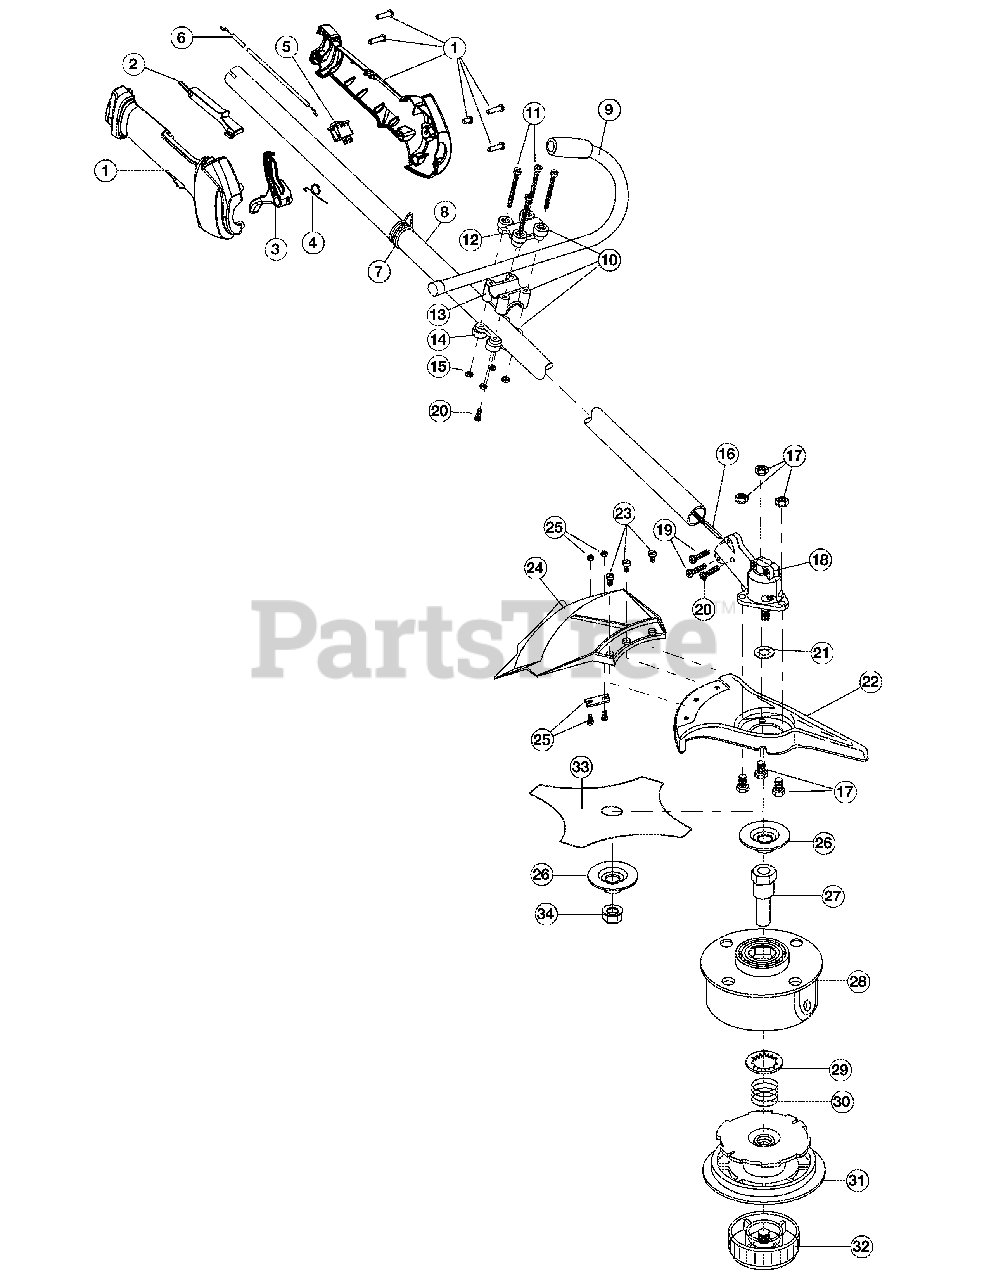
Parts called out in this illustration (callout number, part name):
1	Throttle Housing Assembly
2	Throttle Trigger Lock-Out
3	Throttle Trigger
4	Throttle Trigger Spring
5	Switch Assembly
6	Throttle Cable Assembly
8	Drive Shaft Housing Assembly
9	J-Handle Assembly
10	Handle Bracket Assembly
12	Upper Handle Clamp
13	Middle Handle Clamp
14	Lower Handle Clamp
16	Flexible Drive Shaft
17	Shield Mount Screw Assembly
18	2 piece Gearbox Assembly
19	Gearbox Mounting Hardware
20	Anti-Rotation Screw
22	Blade Shield/Shield Mount
23	Shield Mounting Screw
24	Shield Assembly
25	Blade Assembly
26	Retaining Washer
28	Outer Spool Assembly
29	Retainer
32	Bump Head Knob Assembly
33	4-Tooth Blade
34	Nut
